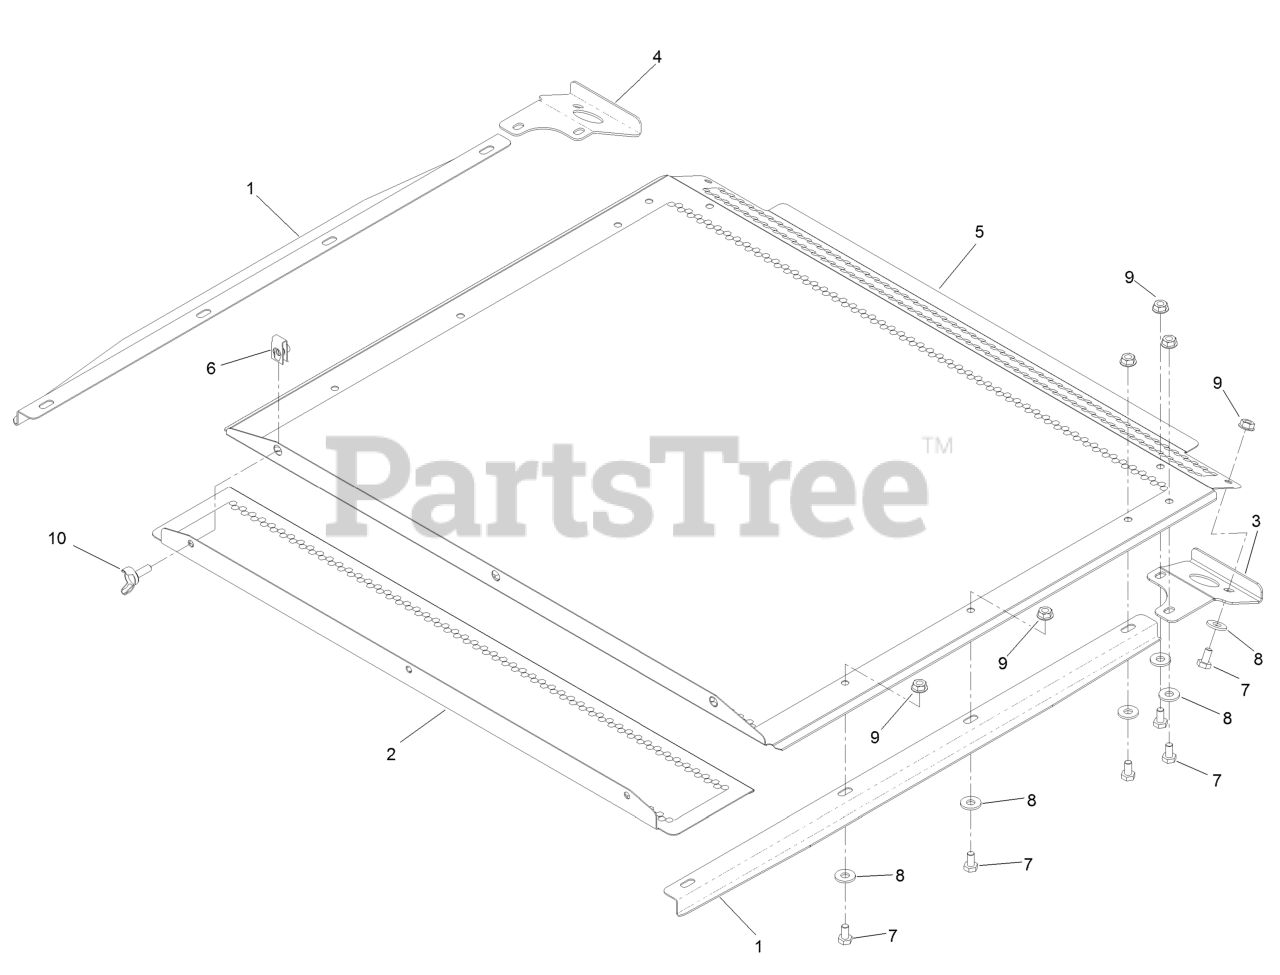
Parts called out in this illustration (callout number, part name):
1	GUIDE-SCREEN
2	PANEL-SCREEN, REMOVABLE
3	HANDLE-SCREEN, LH
4	HANDLE-SCREEN, RH
5	PANEL-SCREEN, HOPPER
7	SCREW-HH
8	WASHER-FLAT
10	SCREW-WING
